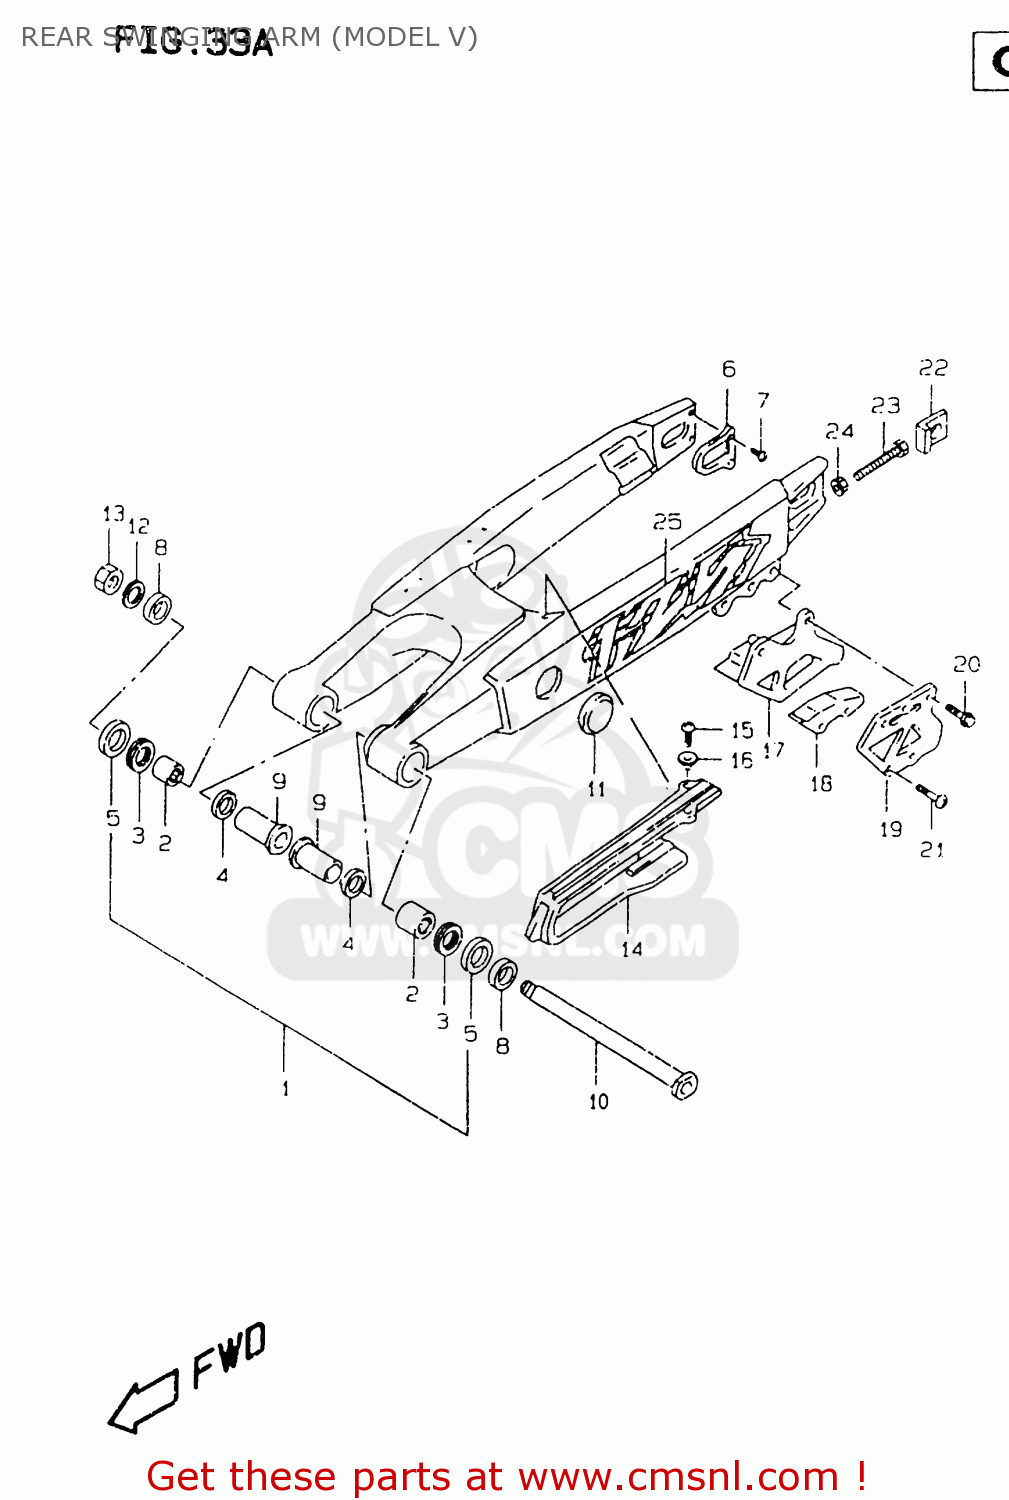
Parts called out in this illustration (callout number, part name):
1	SWING ARM ASSEMBLY,REAR
2	BEARING(22X29X30)
3	BEARING(22X35X2)
4	SEAL,OIL(22X29X4)
5	SEAL,RR SWGARM PIVOT OUTER
6	PLATE,SWING ARM,REAR
7	SCREW(5X8)
8	SPACER,RR SWGARM PIVOT OUTER
9	SPACER,SWGARM PIVOT INNER
10	SHAFT,RR SWINGINGARM PIVOT
11	CAP(OD:45)
12	WASHER, FIXED DRIVE FACE
13	NUT
14	BUFFER,CHAIN TOUCH DEFENSE
15	SCREW
16	WASHER
17	GUIDE,CHAIN
18	DEFENSE,CHAIN GUIDE
19	PLATE,CHAIN GUIDE OUTER
20	SCREW
21	SCREW(6X40)
22	WASHER,CHAIN ADJUSTER
23	BOLT(8X50)
24	NUT
25	EMBLEM,SWING ARM
